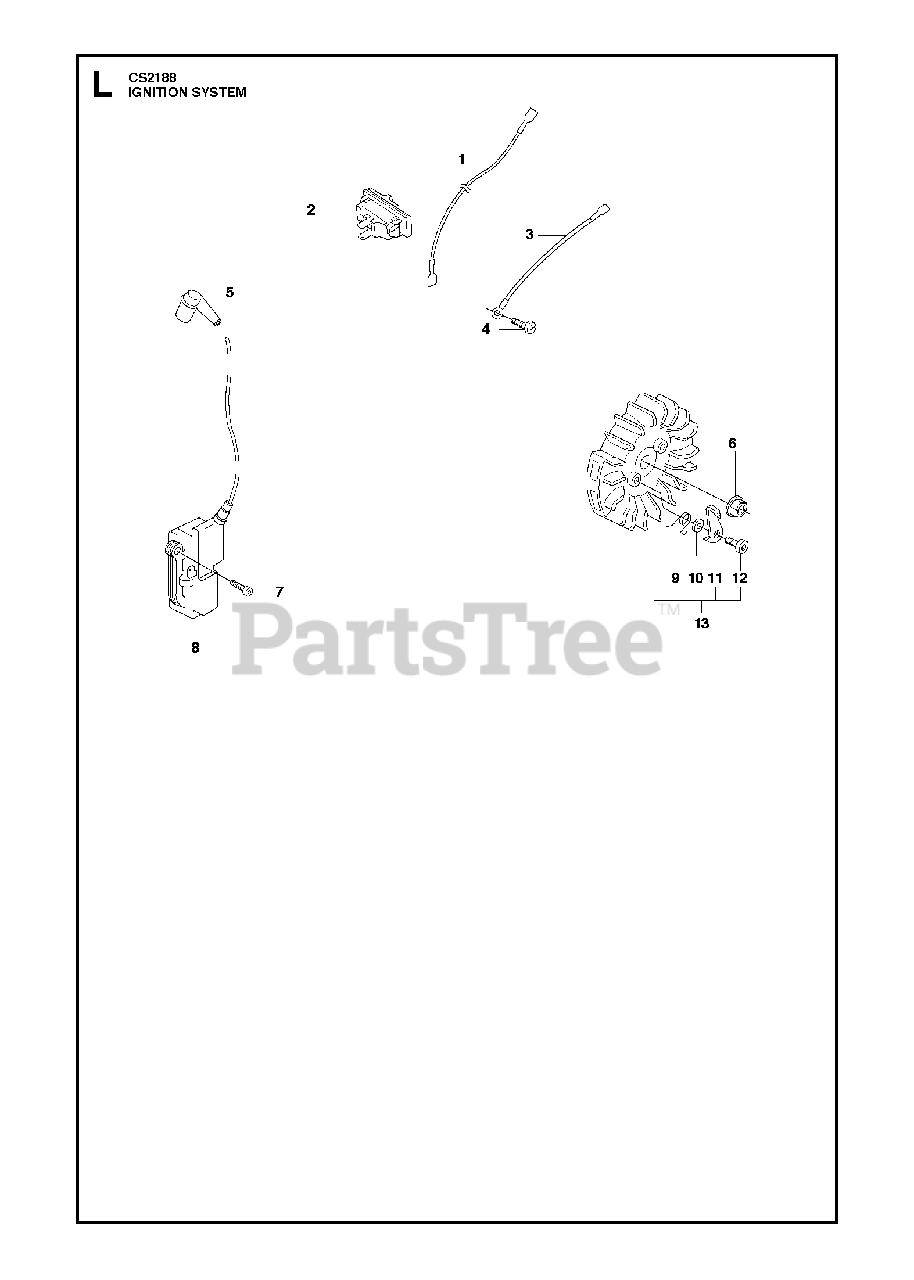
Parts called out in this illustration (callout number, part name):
2	START/STOP SWITCH
5	SPARK PLUG CONN. KIT
6	NUT W/ WASHER
8	IGNITION MODULE
9	SPRING
10	WASHER
11	PAWL
12	SCREW M5X14
